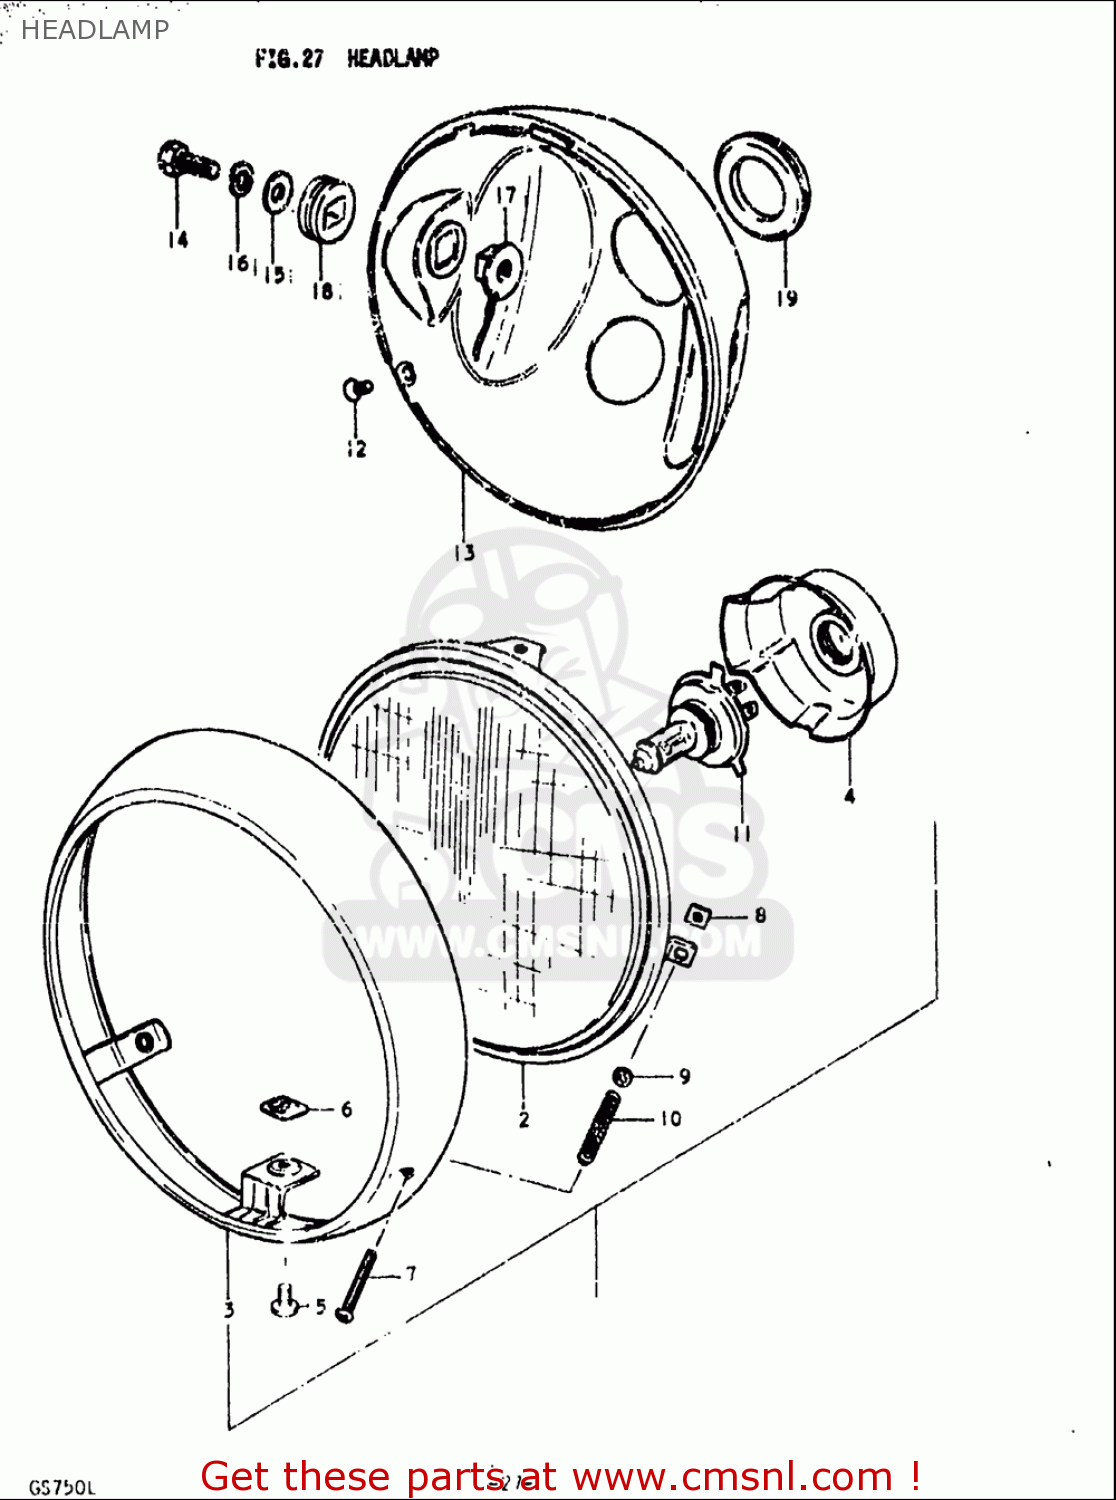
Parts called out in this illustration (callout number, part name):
3	RIM
5	SCREW
6	NUT
7	SCREW
8	NUT
9	WASHER
10	SPRING
11	BULB(12V60/55W,H4)
12	SCREW
13	HOUSING,HEADLAMP
14	BOLT
15	WASHER
16	WASHER,LOCK
17	SPACER,HEADLAMP HOUSING
18	CUSHION,HEADLAMP HOUSING
19	GROMMET,HEADLAMP HOUSING
